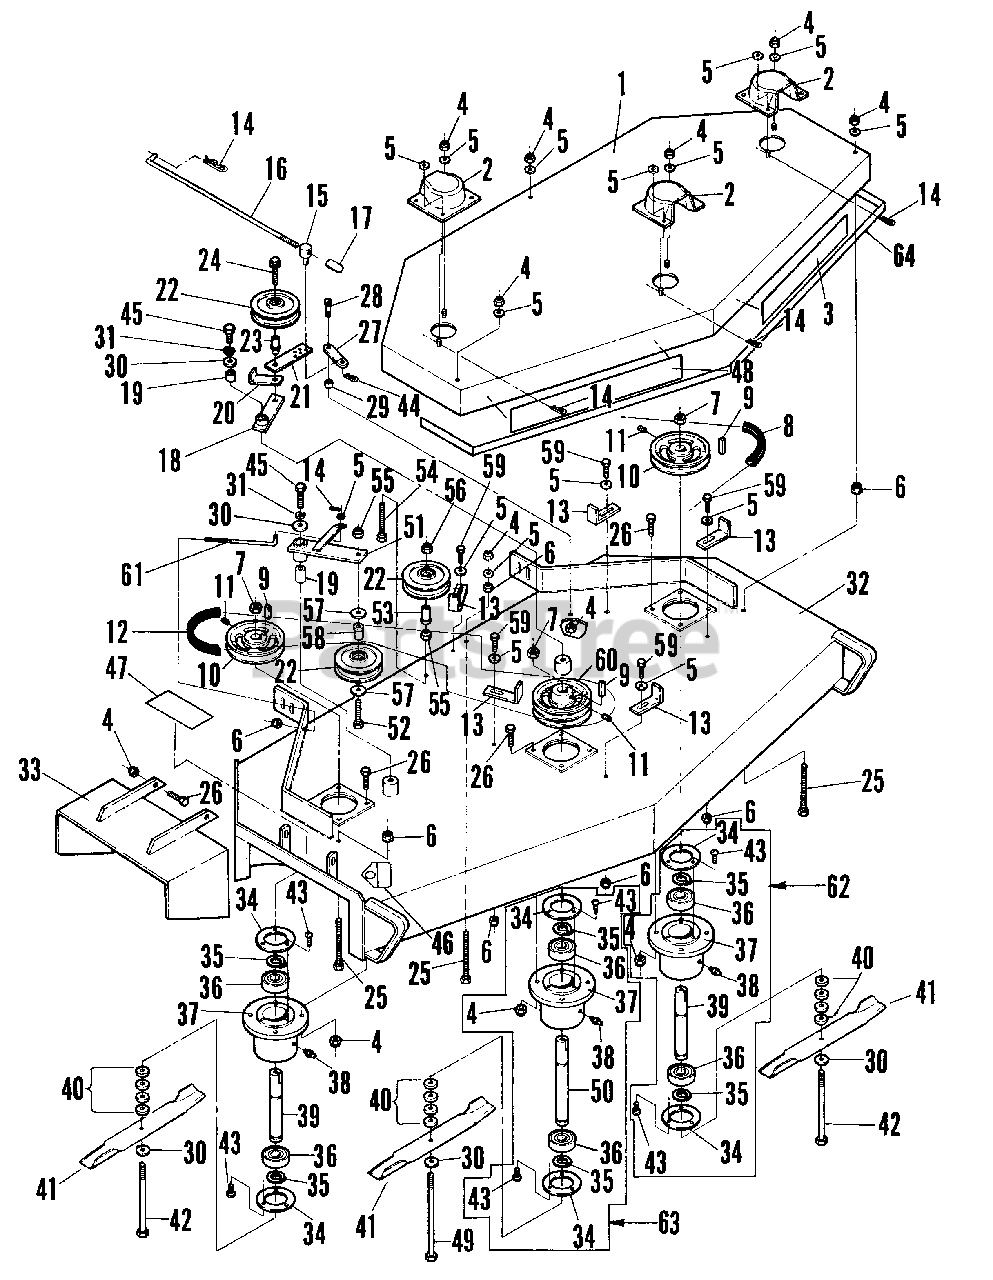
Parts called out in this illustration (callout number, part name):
1	BELT COVER W/DECALS
2	COVER, Spindle
3	DECAL, 48 Inch
4	NUT, 5/16-18 Nyloc Hex
5	WASHER, 5/16 Std. Flat
6	NUT, 5/16-18 Whizlock
7	NUT, 5/8-18 Hex
8	BELT, Engine/Blade
9	KEY, 1/4 Square x 1 1/4
10	PULLEY, w/Set Screws
11	SCREW, Set
12	BELT, Blade to Blade
13	GUIDE, Belt
14	COTTER, #2 Hairpin
15	SWIVEL
16	ROD, Blade Drive
18	ARM, Idler w/Bushing
19	BUSHING
20	SNUBBER, Belt
21	ARM, Tightening
22	PULLEY, Idler
23	BUSHING, Flange
24	BOLT, Flange Lock 3/8-16 X 1 3/4
25	SCREW, Hex Head Cap 5/16-18 x 3 1/4
26	SCREW, Hex Head Cap 5/16 - 18 x 1 GR. 5
27	ARM, Blade Assist
28	BOLT, Knurled Socket Head Shoulder 3/8 x 3/4
30	WASHER, Flat 5/8
31	WASHER, Lock 5/8
32	DECK, Front 48 w/Decals
33	DEFLECTOR, Chute
34	CAP, CUTTER HOUSING
35	RING, RETAINING
36	BEARING (Single Seal)
37	HOUSING, CUTTER
38	ZERK, 1/8 NPT
39	SPINDLE, CUTTER
40	SPACER, Blade
41	BLADE, 16 1/4 High Lift (.204)
42	SCREW, Hex Head Cap 5/8 - 18 x 7 1/2
43	SCREW, SELF-TAPPING 10 - 24 x 1/2
44	COTTER, Hairpin #4
45	SCREW, Hex Head Cap 5/8 - 11 x 1
46	DECAL, CPSC
47	DECAL, "Caution"
48	DECAL, "SNAPPER"
49	SCREW, Hex Head Cap 5/8 -18 x 8"
50	SPINDLE CUTTER
51	ARM, Idler Right w/Bushing
52	SCREW, Hex Head Cap 3/8 - 16 x 2
53	BUSHING, Idler Flange
54	BOLT, Hex Head Tap 3/8 - 16 x 2 1/2
55	NUT, Nyloc Hex 3/8 - 16
56	NUT, Whizlock 3/8 - 16
57	WASHER
58	BUSHING, Idler Flange
59	SCREW, Hex Head Cap 5/16 - 18 x 3/4
60	PULLEY, Double w/Set Screws
61	ROD, Belt Tension
62	ASSEMBLY CUTTER HOUSING,
63	ASSEMBLY CUTTER HOUSING (CTR)
64	DECAL, STRIPE
